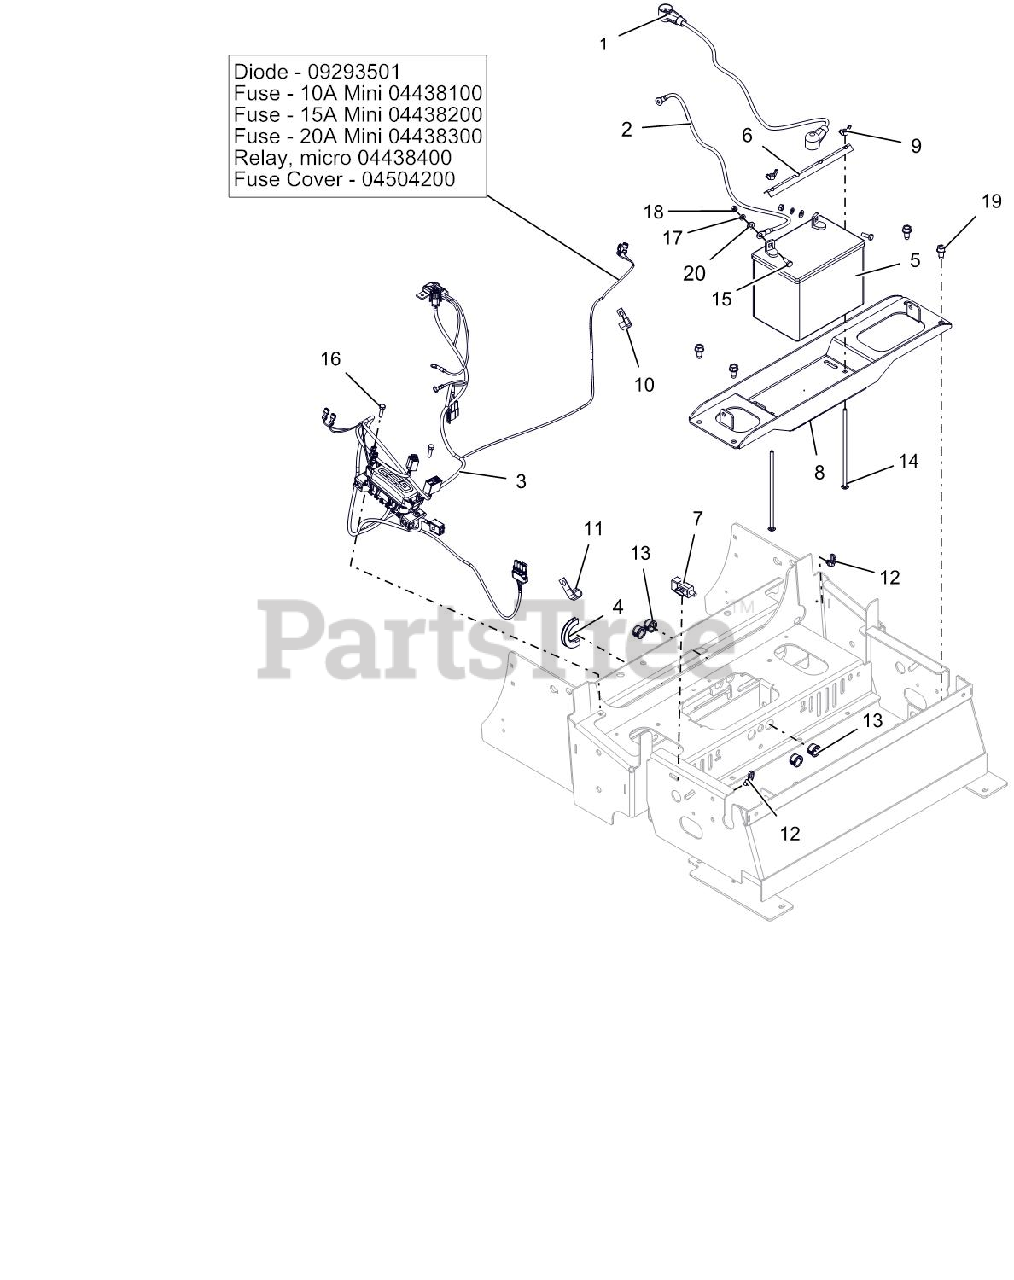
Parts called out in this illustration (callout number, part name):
1	CABLE - POS BATT W/BOOTS 6X35
2	CABLE-NEGATIVE BATTERY 35.00"
3	FUSE,10 AMP MINI-ATC
3	FUSE,20 AMP MINI ATC
3	RELAY,MICRO5 TERML W/RESISTOR
3	COVER, HARNESS FUSE/RELAY MOD
3	FUSE,15 AMP MINI-ATC
3	DIODE, CONNECTOR SHELL
3	HARNESS, PT400 WIRING
4	STRIP, COWL
5	BATTERY, 300 CCA 10U1L
6	HOLD DOWN
7	SWITCH, SNAP IN - N.O./N.O.
8	PT400 GAS BATTERY TRAY - RED
9	NUT-LK WING .250-20 YWZC
12	CABLE TIE W/ TREE (.25 HOLE)
13	BUSH, PANEL SNAP .687X.875X.56
14	BLT-RDHDSQNK .25-20X7.50 GR2YZ
15	@BLT-HEX .25-20X.75 GR5 YWZC
16	@BLT-HEX M6-1.0X25 YWZC
17	@WSHR-LK .25X.062 REG YWZC
18	@NUT-HEX .25-20 YWZC
19	@SCR-TAP .38-16X.75 HWH TR YWZ
20	@WSHR-FL-STL.281X.62X.065 YWZC
